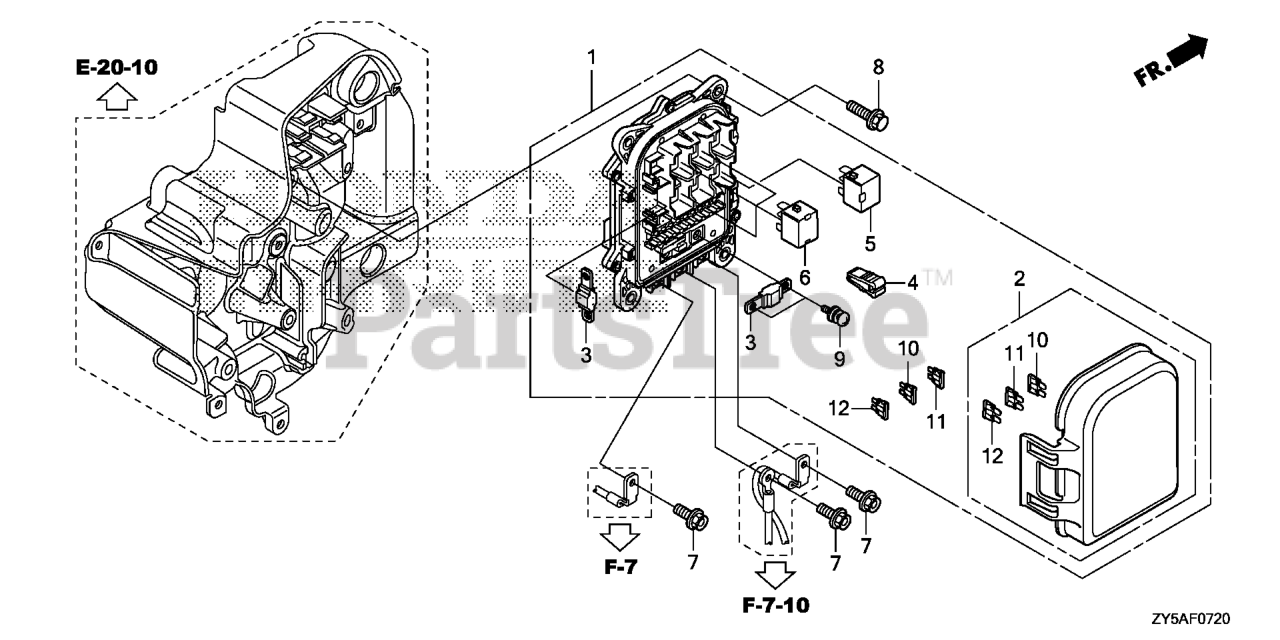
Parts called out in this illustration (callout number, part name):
1	BOX ASSY., JUNCTION
2	COVER, FUSE
3	FUSE, BLOCK (100A) (L-TYPE)
4	PULLER, MINI FUSE
5	RELAY ASSY., FUEL PUMP (DENSO)
6	RELAY ASSY., POWER (12V-20A) (MICRO ISO 4P)
7	BOLT, FLANGE (6X12)
8	BOLT, FLANGE (6X20)
9	SCREW-WASHER (5X15)
10	FUSE, MINI (10A)
11	FUSE, MINI (15A)
12	FUSE, MINI (30A)
